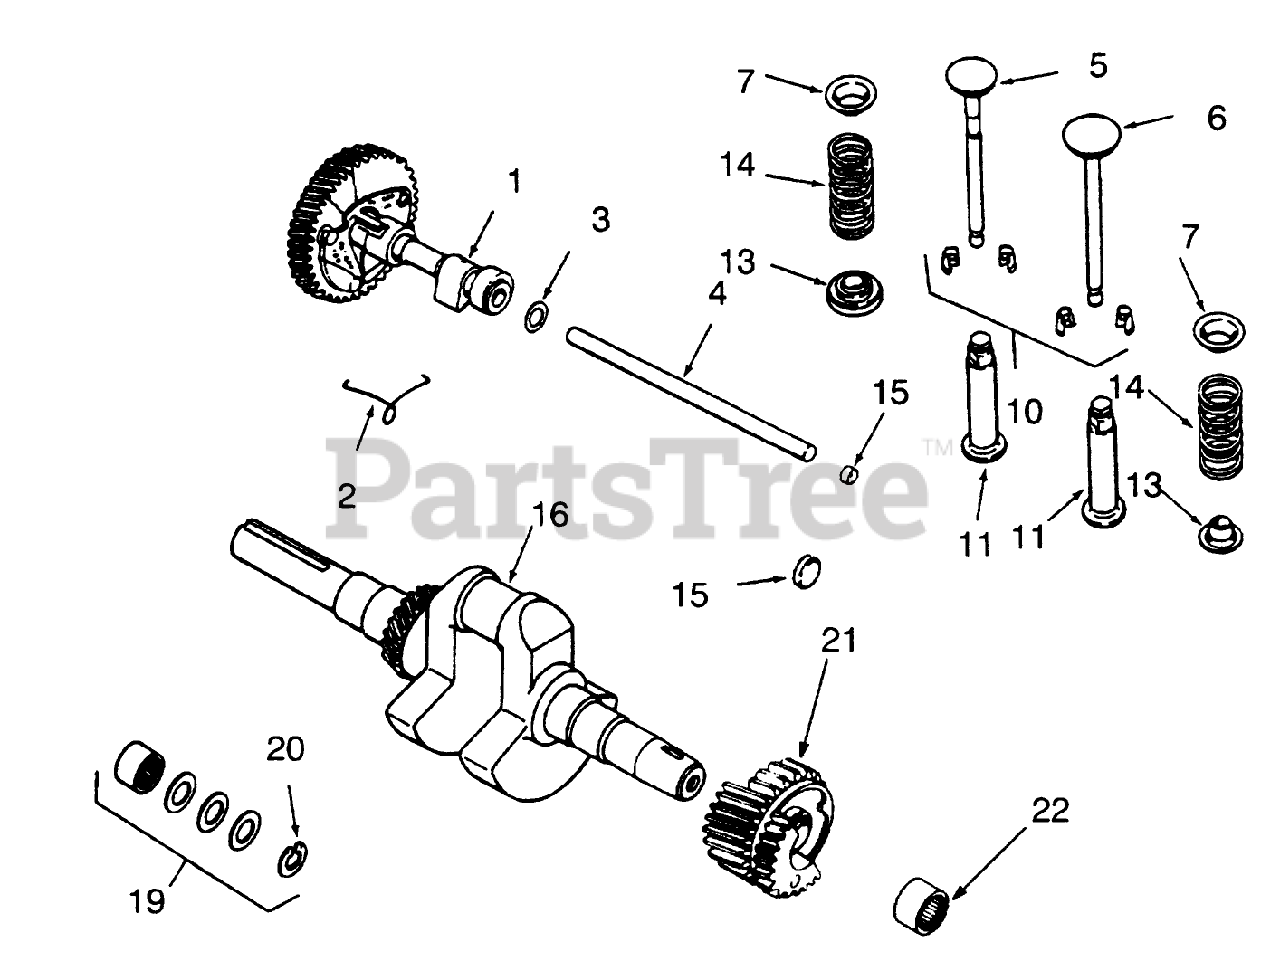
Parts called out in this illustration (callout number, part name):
1	KOHLER 47-010-11
2	KOHLER 47-089-01
3	KOHLER 275066
4	KOHLER 47-380-09
5	KOHLER 237672
6	KOHLER 235582
7	KOHLER 235011
10	KOHLER 41-755-10
11	KOHLER D-235327
13	KOHLER 52-413-01
14	KOHLER 235168
15	KOHLER X-702-3
16	KOHLER 45-142-21
19	KOHLER 47-755-01
20	KOHLER X-269-34
21	KOHLER 45-043-03
22	KOHLER 47-030-01
